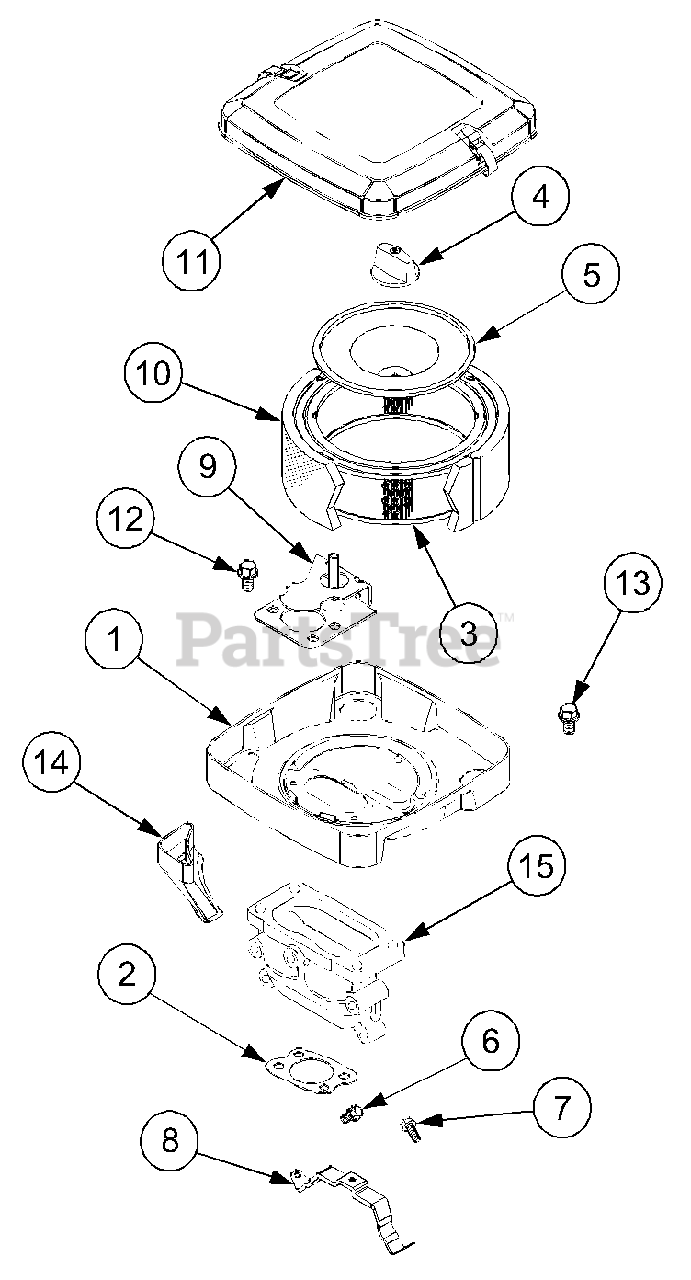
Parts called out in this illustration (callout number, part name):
1	Base, Air Cleaner
2	Gasket, Air Cleaner
3	Filter, Air Cleaner Cartridge
4	Knob, Air Cleaner
5	Retainer, Air Filter
6	Screw, Cleaner Mounting Strap
7	Screw, Cleaner Mounting Strap
8	Strap, Air Cleaner Mounting
9	Shield, Carburetor
10	Pre Cleaner, Filter
11	Cover, Air Cleaner
12	Screw, Air Cleaner Base
13	Screw, Air Cleaner Base
15	Elbow, Intake
